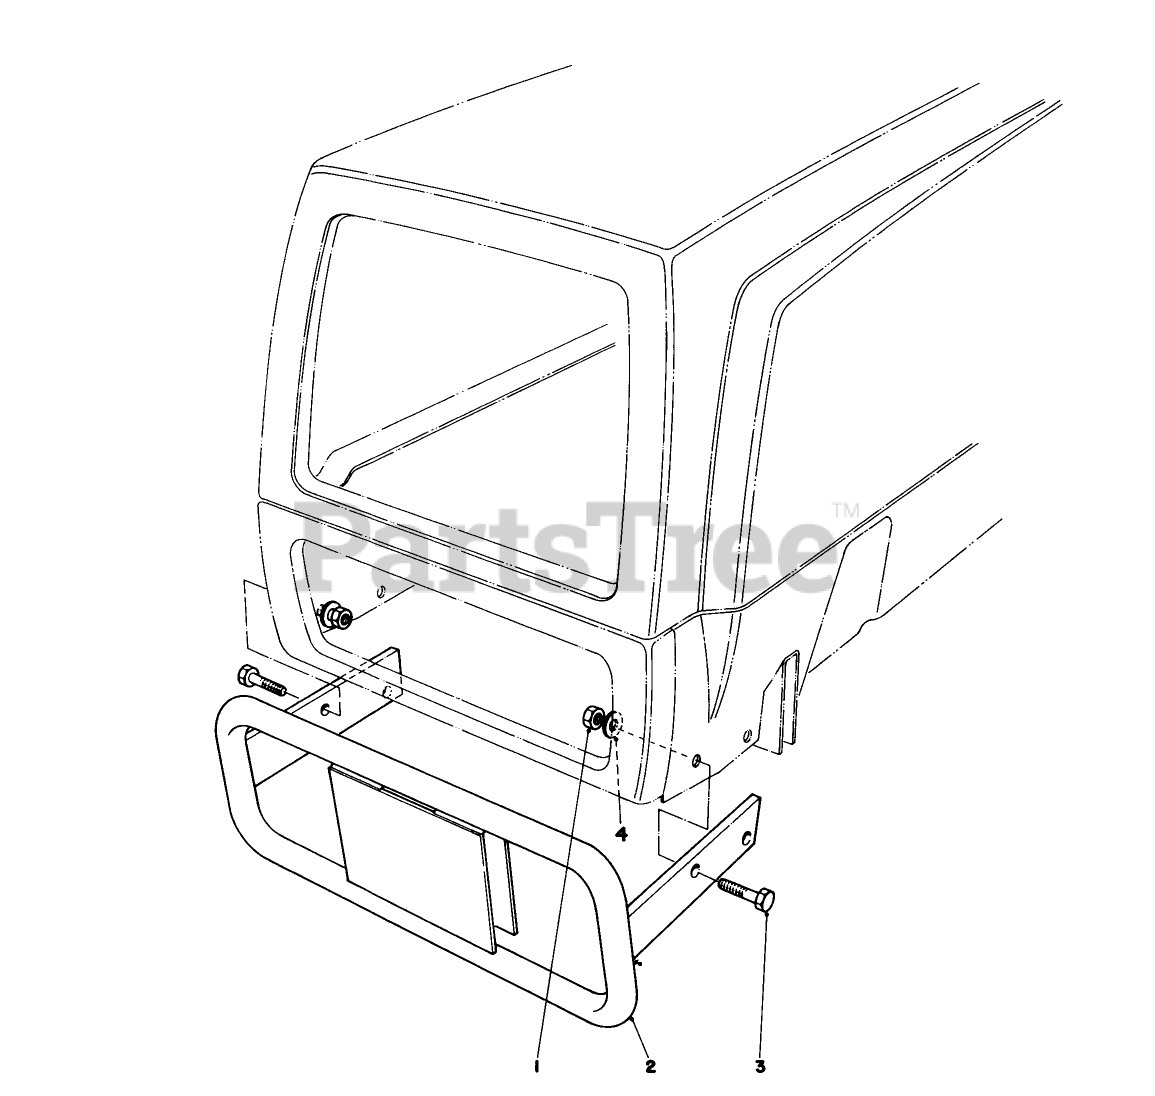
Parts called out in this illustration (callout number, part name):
1	NUT-LOCK, CONE
2	Bumper W.A.
3	SCREW-HH
4	WASHER-PLAIN
